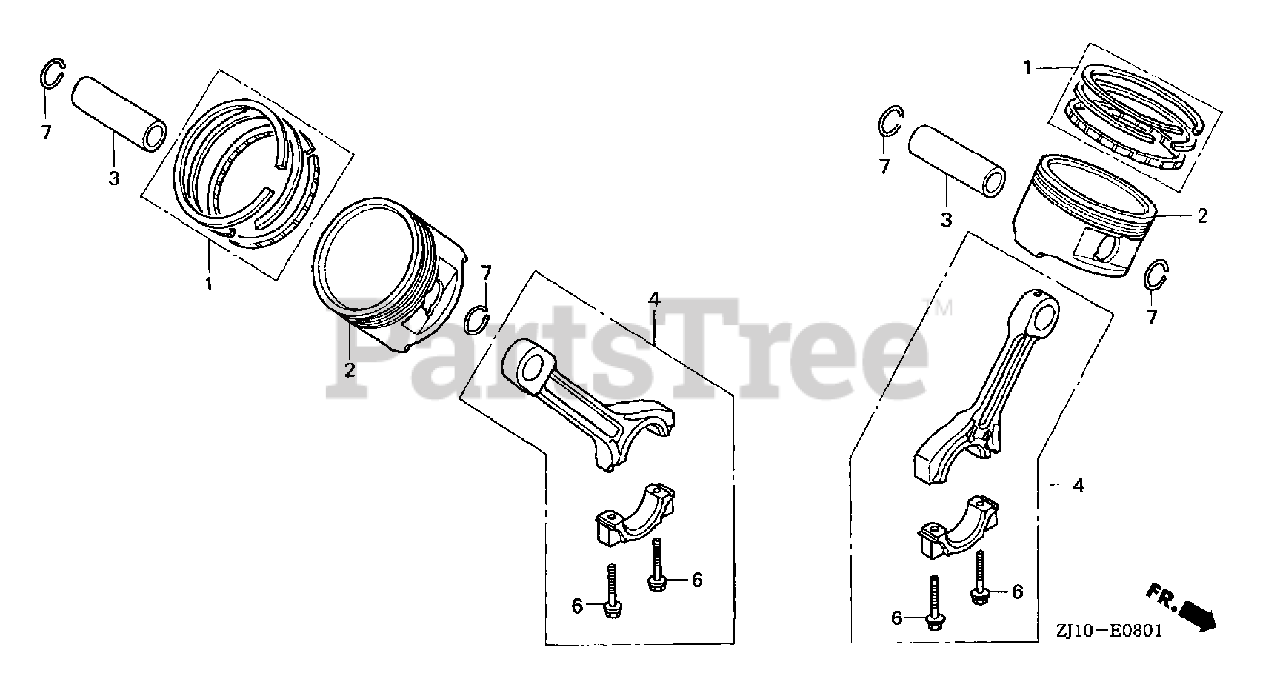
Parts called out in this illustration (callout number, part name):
1	Ring Set, Piston (Std)
2	Piston (Std)
3	Pin, Piston
4	Rod Assembly, Connecting
6	Bolt, Connecting Rod (6x37)
7	Clip, Piston Pin (18mm)
